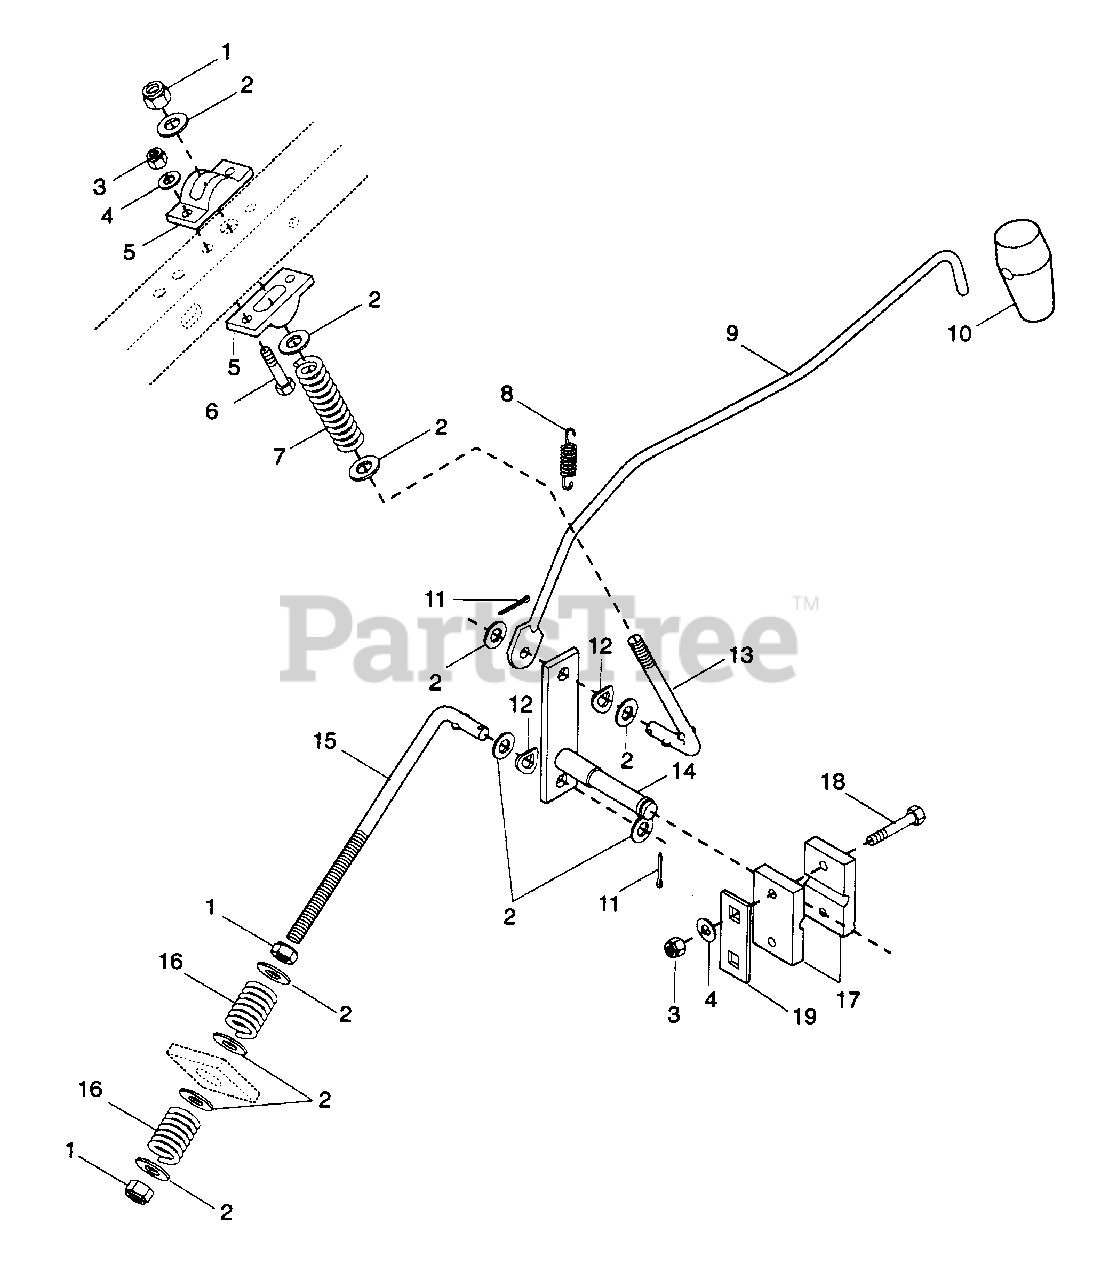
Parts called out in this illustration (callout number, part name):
1	NUT-LK-NYL .375-16 PL
2	WSHR-FL-STL .406 X .812 X .065 PL
3	NUT-LK-NYL .250-20 PL
4	WSHR-FL-STL .281 X .62 X .065 PL
5	CAM, SHIFTER
6	BLT-HEX .25-20 X 1.00 PL GR 5
7	SG-COMP .081 X .720 X 2.75 PL
8	SG-TENS .041 X 1.25 X .50 PL
9	ROD, SHIFTER
10	HNDL, RUBBER SHIFTER
11	PIN-COTR .12 X .75 PL
12	SPRING WASHER
13	LINK, SHIFTER STOP
14	WLDMT, SHIFTER CRANK
15	LINK, SHIFTER
16	SG-COMP .125 X .78 X 1.00
17	BLOCK, SHIFT LEVER
18	BLT-HEX .25-20 X 1.50 PL GR 5
19	SHIM, MOWER HT. ADJ. BRT.
